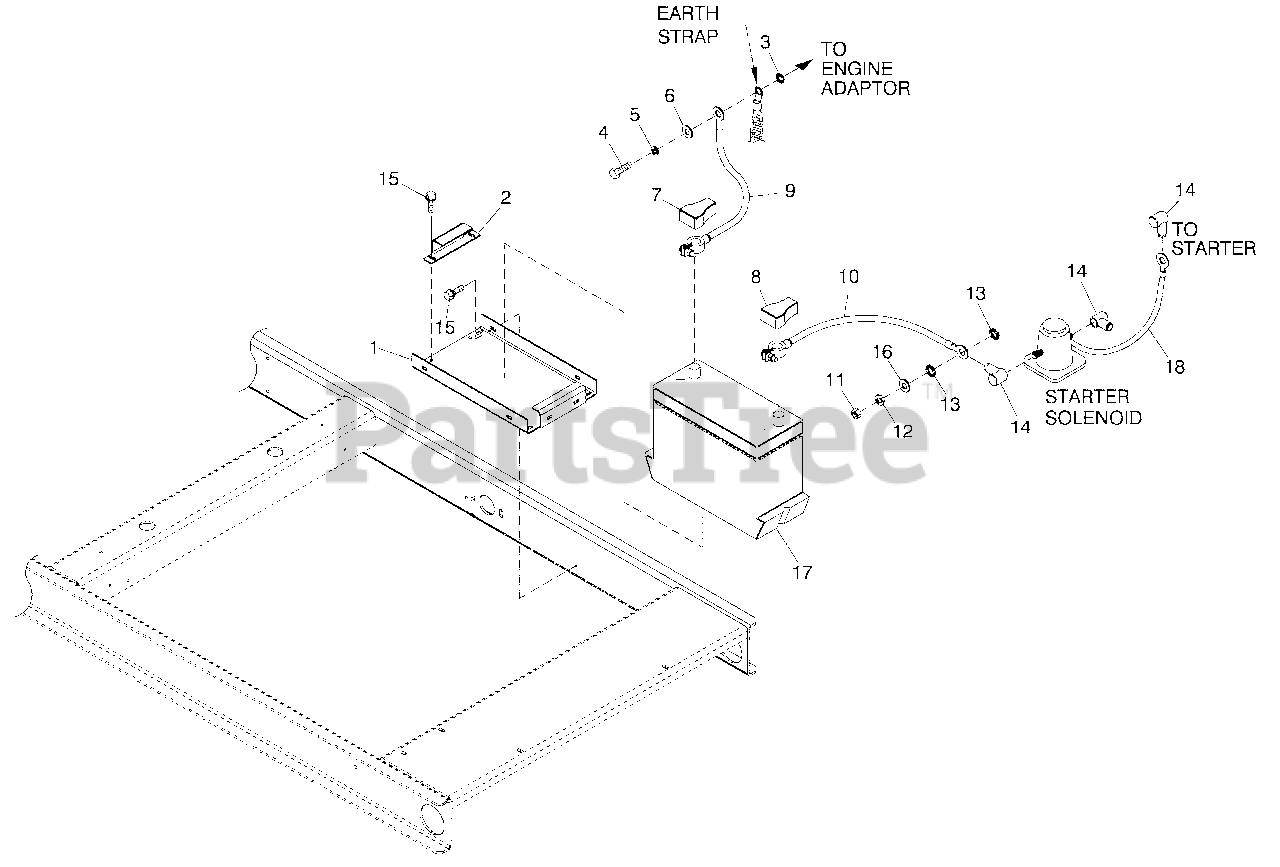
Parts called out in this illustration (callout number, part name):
1	BATTERY TRAY C1 CPL
2	STRAP BATTERY RETAINMENT
3	WASHER SHAKEPROOF EXT 7/16 STL
4	SCREW SHC M10'1.5 X 25 G12.9
5	WASHER LOCK M10
6	WASHER FLAT 3/8'M10 ZINC
7	BATT POST COVER RED +
8	BATT POST COVER BLK '
9	CABLE BATTERY BLK #1 X 30.00
10	CABLE BATTERY RED #1 X 28.00
11	NUT HEX M8'1.25 G8 YEL CHR
12	WASHER LOCK M8'5/16
13	WASHER SHAKEPROOF EXT 5/16 STL
14	BOOT CONTACTOR CABLES
15	SCREW THF M6'1 X 16 N WA Z/JS
16	WASHER FLAT 5/16'M8 ZINC
17	BATTERY 12VDC 75'AH 26
18	ASSY WIRE #16 RED 1.6
